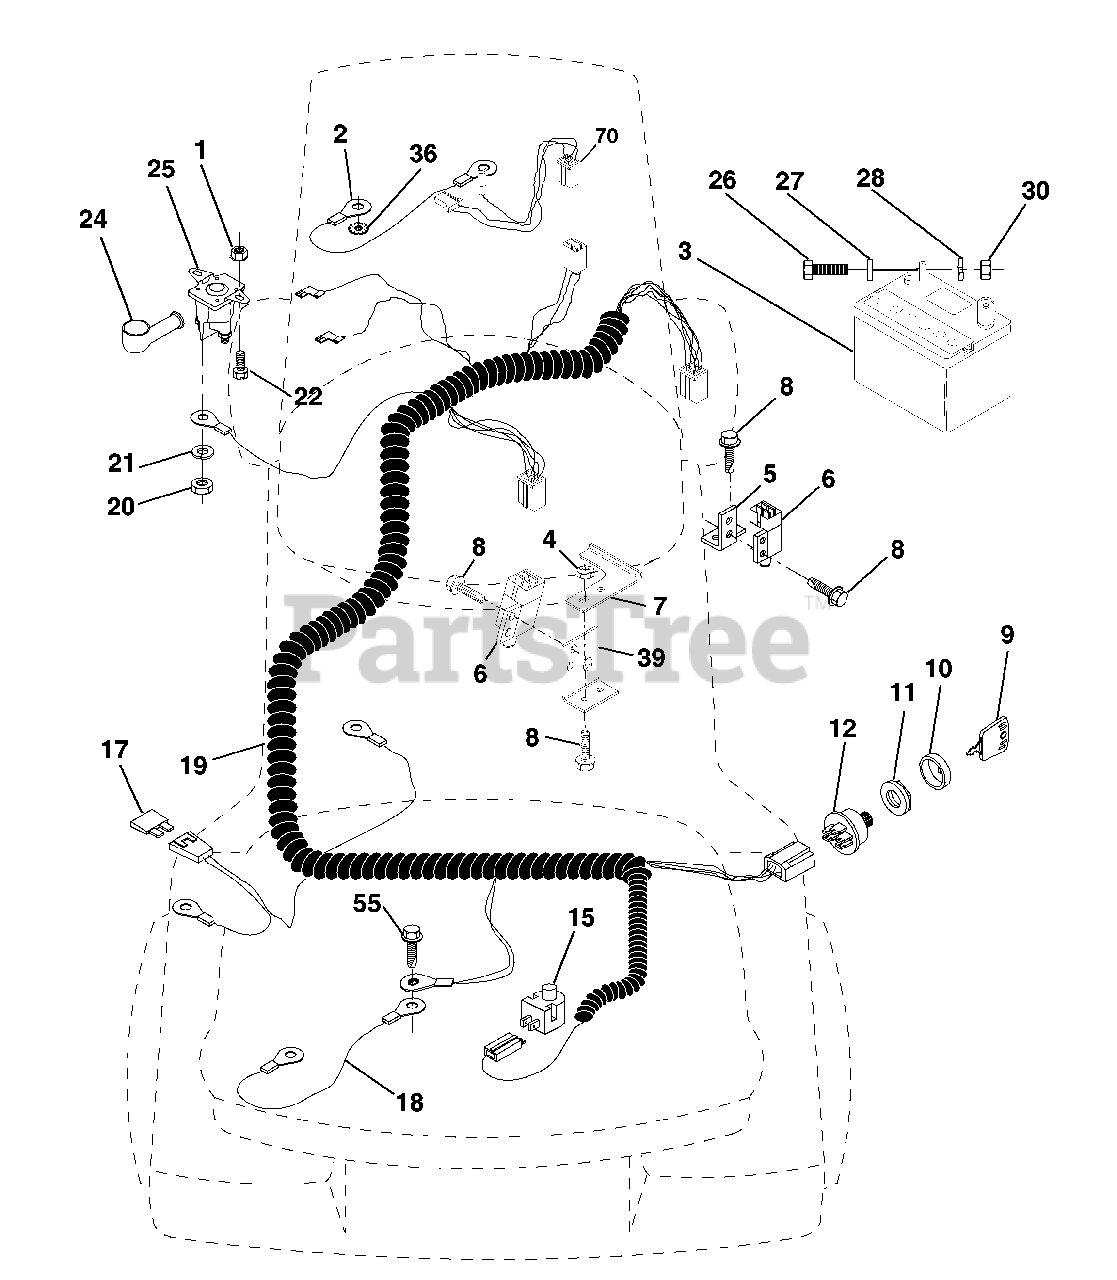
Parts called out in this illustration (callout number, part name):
1	Nut, Hex Keps 1/4-20
2	Assembly, Cable
3	Battery
4	Nut, Lock #10-24 UNC
5	Bracket, Switch
6	Switch, Interlock (4-terminal)
7	Keeper Actuator
8	Screw, Hex Hd. Tap #10-24 x 1/2
9	Key, Steel Delta
10	Cover, Key Ignition
11	Nut, Ignition
12	Switch, Ignition
15	Switch, Plunger
18	Assembly, Cable
19	Harness, Ignition
20	Nut, Hex Jam 1/4-20
21	Washer, Lock 1/4
22	Bolt, Fin. Hex 1/4-20 UNC x 1/2 Gr. 5
24	Cover, Terminal
25	Solenoid
26	Bolt, Hex Hd. 1/4-20 UNC x 3/4
27	Washer 9/32 x 5/8 x 16
28	Washer, Lock 1/4
30	Nut, Fin. Hex 1/4-20 UNC
36	Washer, Lock Inter. Tooth 1/4
39	Bracket, Switch Clutch
55	Screw Thdrol 5/16-18 x 1/2
70	Harness, Engine
